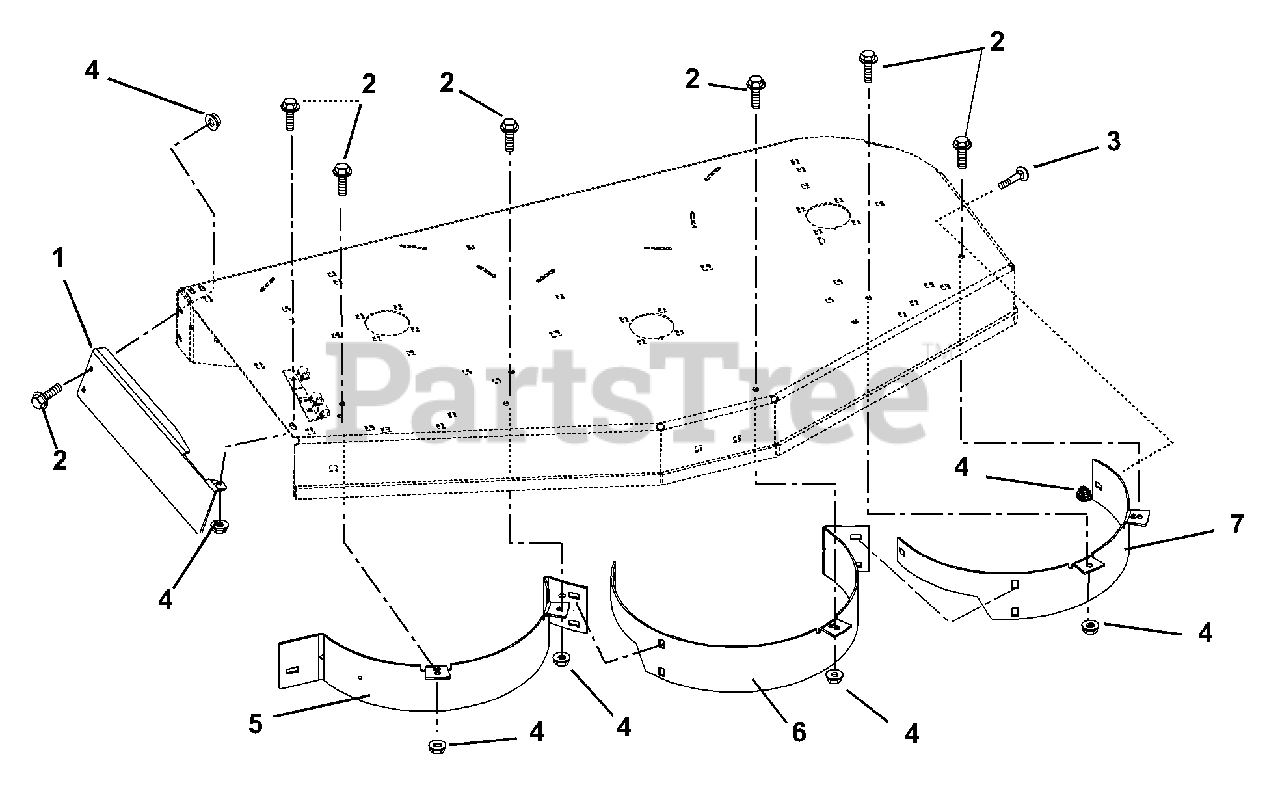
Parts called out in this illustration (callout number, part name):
1	BLOCK-OFF PLATE
2	BLT-SERHFWH .312-18X.75 YWZC
3	@BLT-RHDSSQNK .31-18X.75 G5YZ
4	@NUT-LK-NYL-FLG .31-18 YWZC
5	BAFFLE-MULCH-RIGHT FRONT-40"
5	BAFFLE-MULCH-RIGHT FRONT-44"
6	BAFFLE-MULCH-CENTER FRONT-40"
6	BAFFLE-MULCH-CENTER FRONT-44"
7	BAFFLE-MULCH-LEFT FRONT-40"
7	BAFFLE-MULCH-LEFT FRONT-44"
